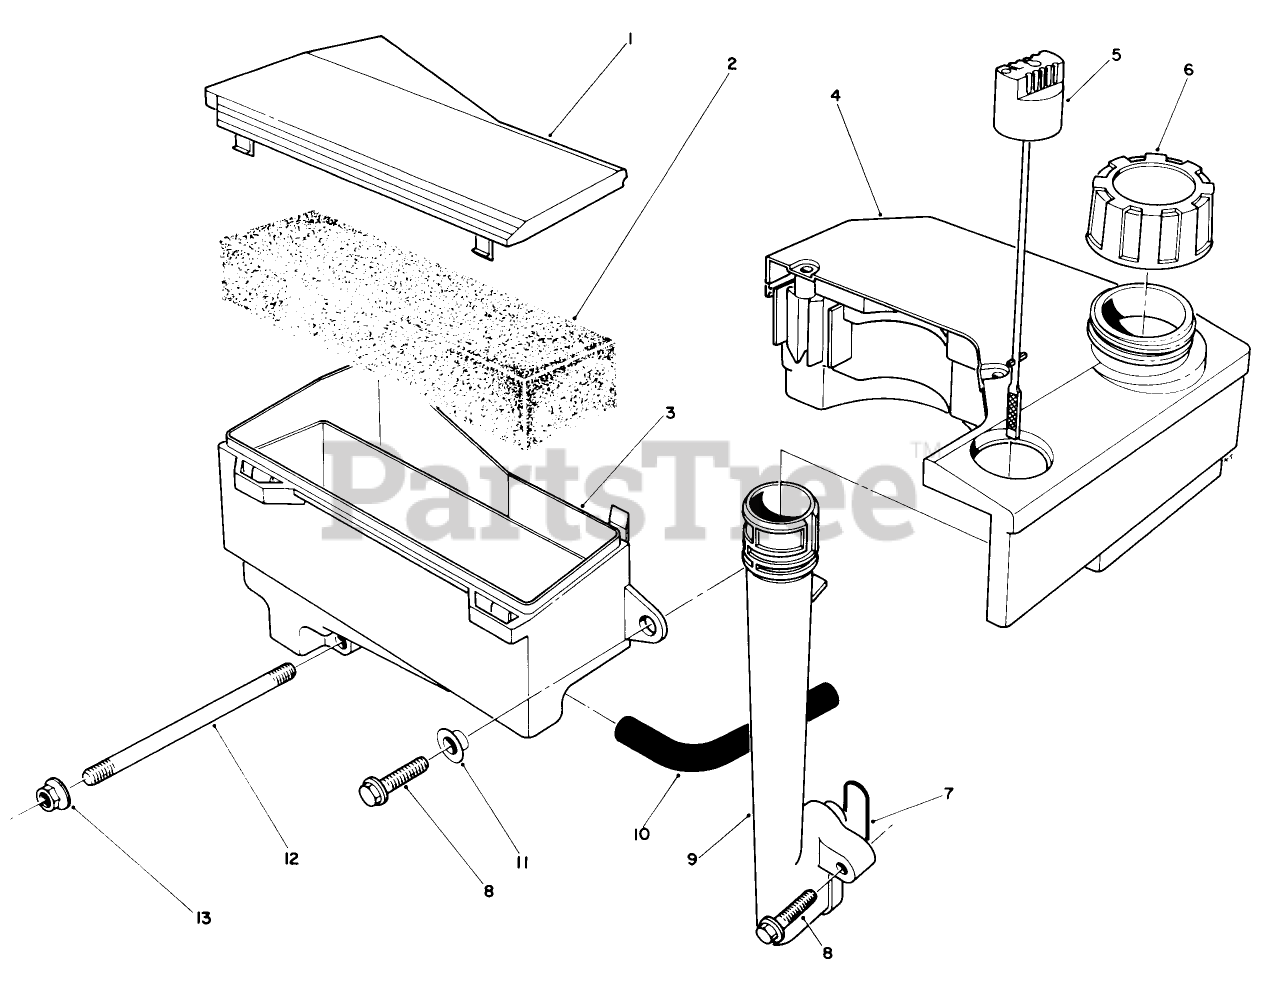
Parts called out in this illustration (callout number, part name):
1	AIR CLEANER CAP
3	Body-Air Cleaner
4	TANK ASM
6	GAS CAP ASM
7	O-RING
11	SPACER
